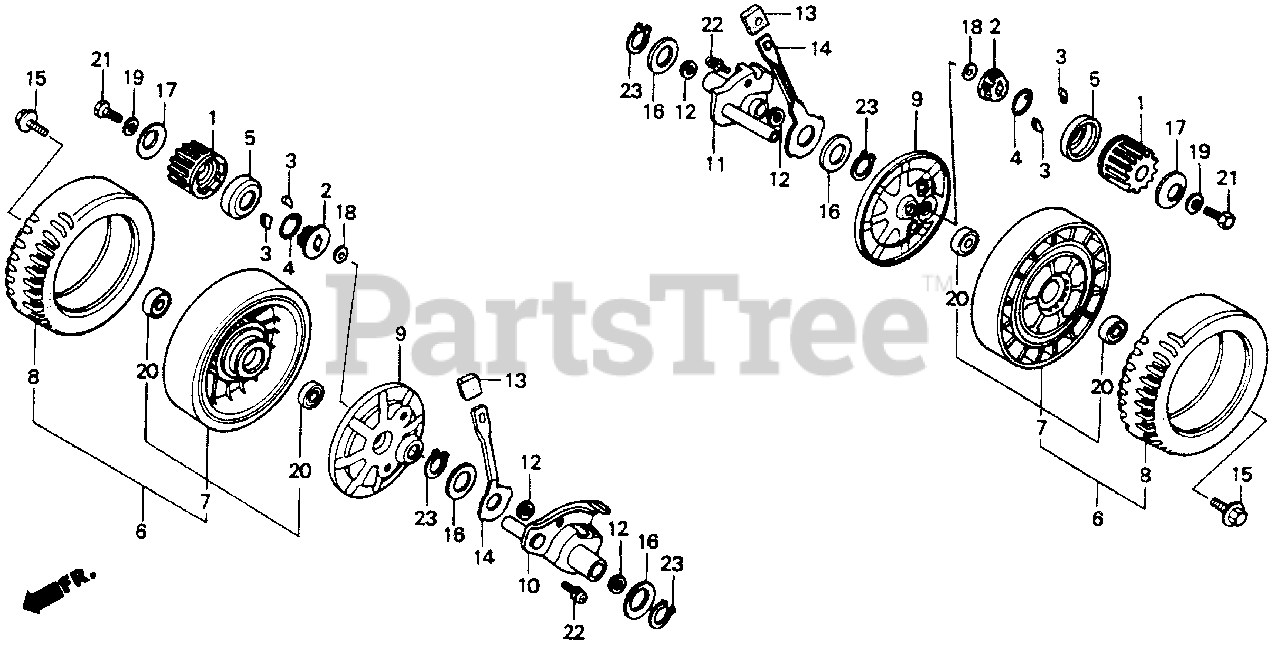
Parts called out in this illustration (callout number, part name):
1	GEAR, PINION
2	HOLDER, RATCHET
4	SPRING, RATCHET RETURN
5	CAP, PINION GEAR
6	WHEEL, RR.
7	HUB, WHEEL
8	TIRE (8 INCH)
9	COVER, WHEEL (NOT AVAILABLE)
10	ARM, R. RR. ADJUSTING (NOT AVAILABLE)
11	ARM, L. RR. ADJUSTING (NOT AVAILABLE)
12	DUST SEAL (12MM)
13	GRIP, ADJUSTER
14	PLATE, RR. ADJUSTING (NOT AVAILABLE)
15	BOLT, WHEEL
16	WASHER, PLAIN (22MM)
17	WASHER (12MM)
19	WASHER, SPARK ADVANCER SETTING
20	BEARING, RADIAL BALL
21	BOLT, HEX. (6X12)
22	SCREW-WASHER (4X14)
23	CIRCLIP (OUTER) (22MM)
